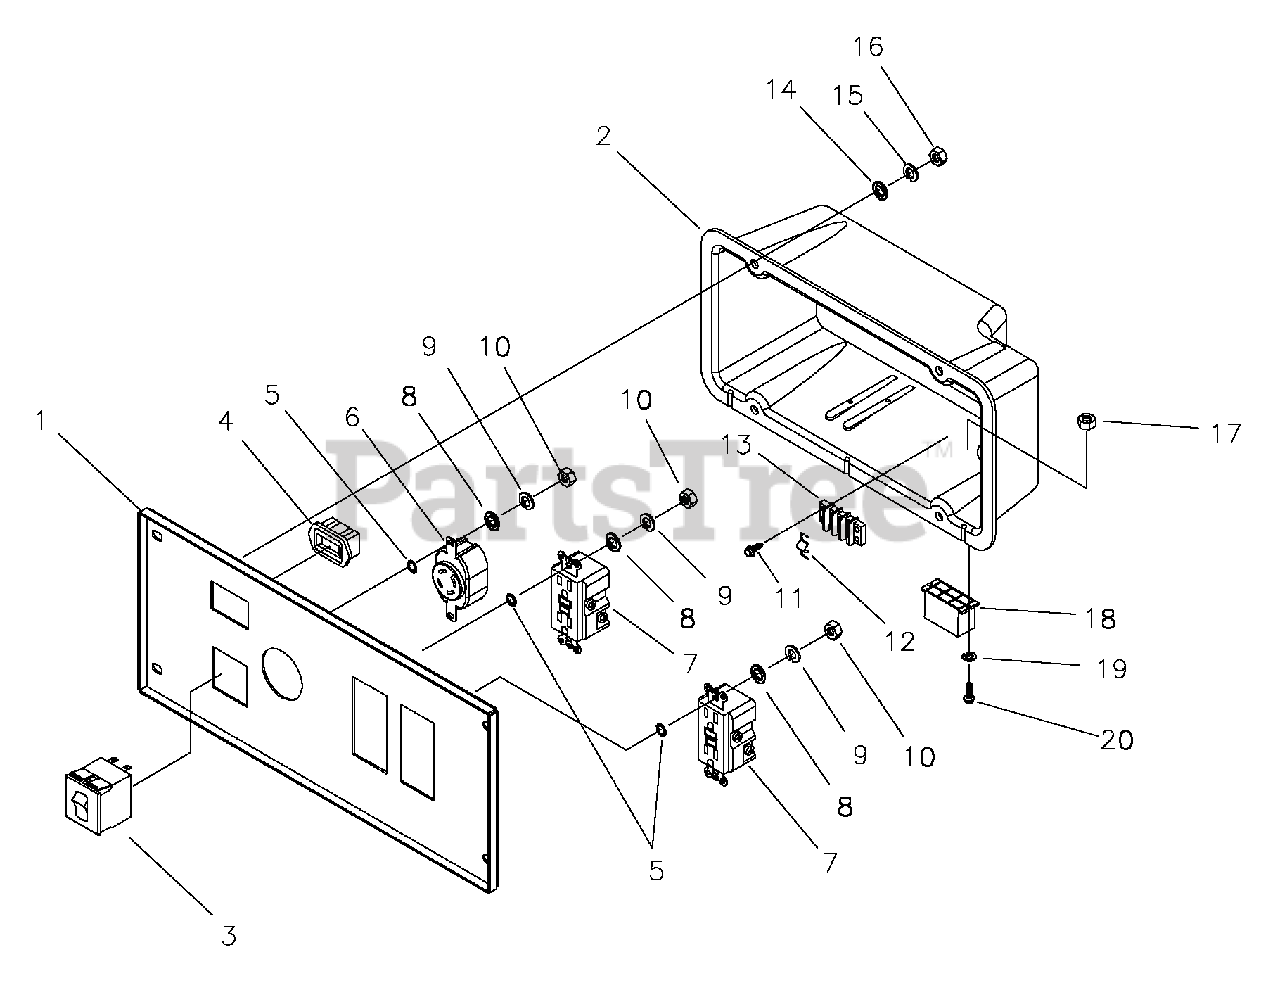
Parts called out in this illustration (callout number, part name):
2	BOX, Control Panel
3	BREAKER, Circuit, 15A
4	METER, Hour
5	WASHER, Shakeproof, Int. #8
6	OUTLET, 120/240V, 20A
7	OUTLET, 120V, 15A Duplex
8	WASHER, Flat, M4
9	WASHER, Lock, M4
10	NUT, M4 - 0.7
11	SCREW, 4 x 18,Tapping
12	JUMPER,Terminal Block
13	STRIP,Terminal, 3 Pole
14	WASHER, Flat, M5
15	WASHER, Lock, M5
16	NUT, M5 - 0.8
17	NUT, M3 - 0.5
19	WASHER, Lock, M3
20	PPHMS, M3 x 18.0
